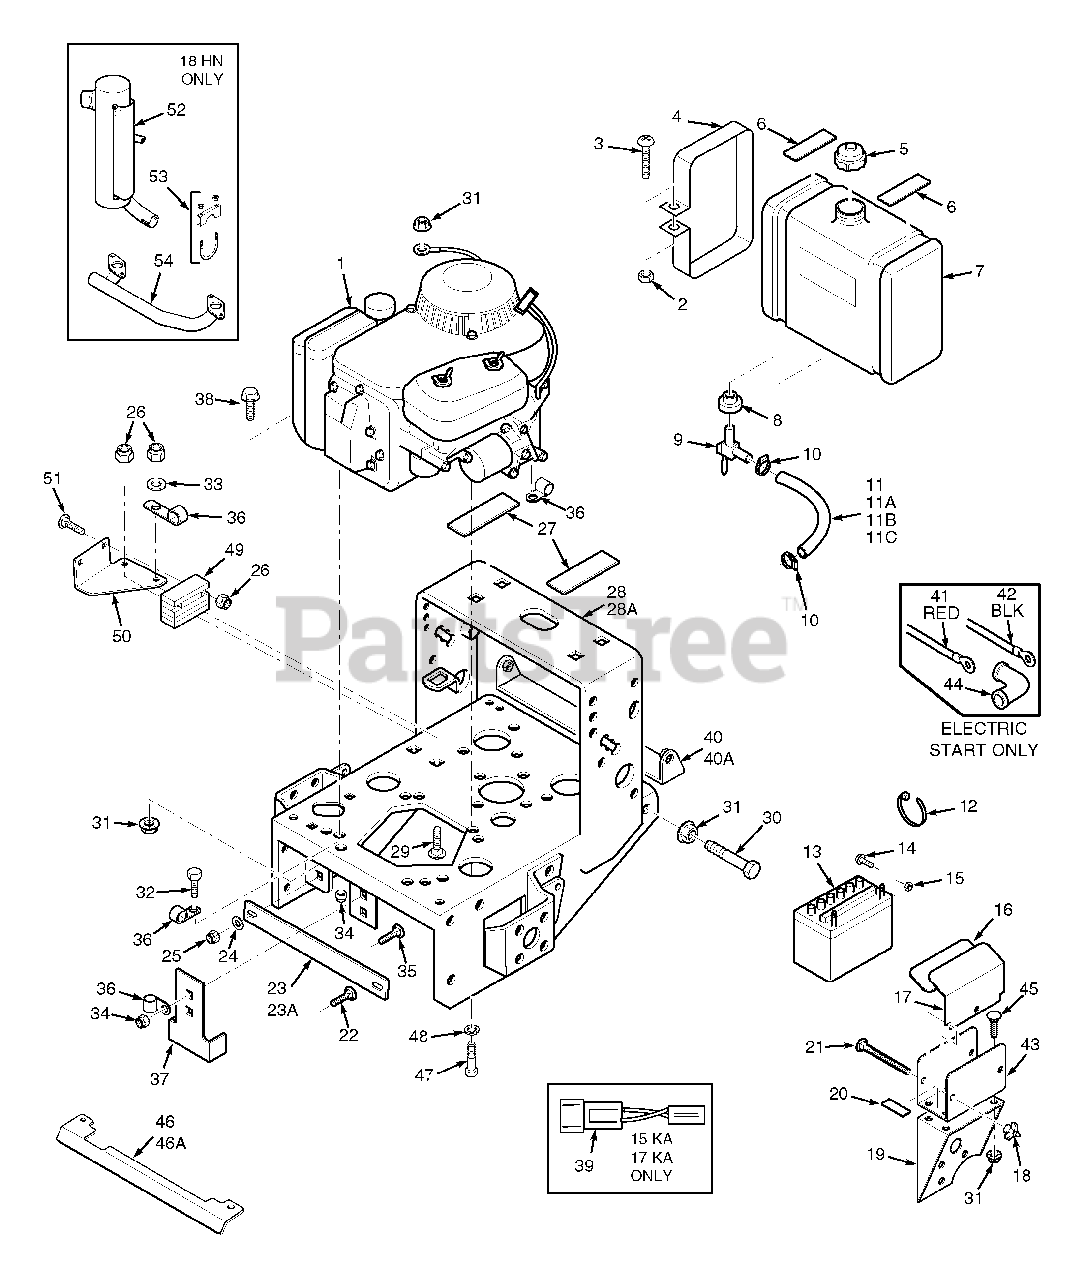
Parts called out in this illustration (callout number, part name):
1	Engine, 18HN Honda
2	Hex Nut, 1/4-20
3	Screw, 1/4-20 x 2" Rnd. Hd. Phil.
4	Strap, Fuel Tank
5	Cap, Fuel Tank
6	Pad, Rubber-Fuel Tank - Upper
7	Fuel Tank Assy.
8	Bushing
9	Valve, Fuel Shut-off
10	Clamp, Fuel Hose
11C	Fuel Hose, 1/4 ID x 26"
12	Cable Tie
13	Battery
14	Bolt, 1/4-20 x 1/2" Hex Head
16	Pad
17	Battery Cover
19	Battery Support
20	Pad, Rubber
22	Bolt, Carriage, 3/8-16 X 1-1/4"
23	Brace, 16"
24	Flat Washer .391 x .938 x .105
25	Nut, 3/8-16 Elastic Stop
26	Nut, 1/4-20 Elastic Stop
27	Pad, Rubber-Fuel Tank Lower
28	Engine Deck, 16" Wide, w/decals
28A	Engine Deck, 20" Wide, w/decals
29	Bolt, Carriage, 1/4-20 x 1-1/4"
30	Bolt, 5/16-18 x 2" Hex Head
31	Nut, 5/16-18 Serr. Flange
32	Hex Head Bolt, 5/16-18 x 3/4"
33	Flat Washer 1/4"
34	Nut, 5/16-18 Elastic Stop
35	Bolt, Carriage, 5/16-18 x 1"
37	Clutch Bracket
38	Cap Scrw, 5/16-18 x 1-1/2" Sr. Flg
39	Wire Hrns. Adapter, 15 &17KA
40	Pulley Guard, 16" Frame
40A	Pulley Guard, 20" Frame
41	Battery Cable, 31-1/2" Red
42	Battery Cable, 31-1/2" Black
43	Battery Box
44	Rubber Boot
45	Bolt, Carriage, 5/16-18 x 3/4"
46	Heatshield (16" Small Frame)
46A	Heatshield (20" Large Frame)
47	Bolt, 5/16-18 x 1" Serrated Flange Hex Head
49	Rectifier
50	Mounting Bracket, Rectifier
51	Bolt, 1/4-20 x 1" Carriage
52	Muffler
53	Clamp, Muffler
54	Manifold, Exhaust
